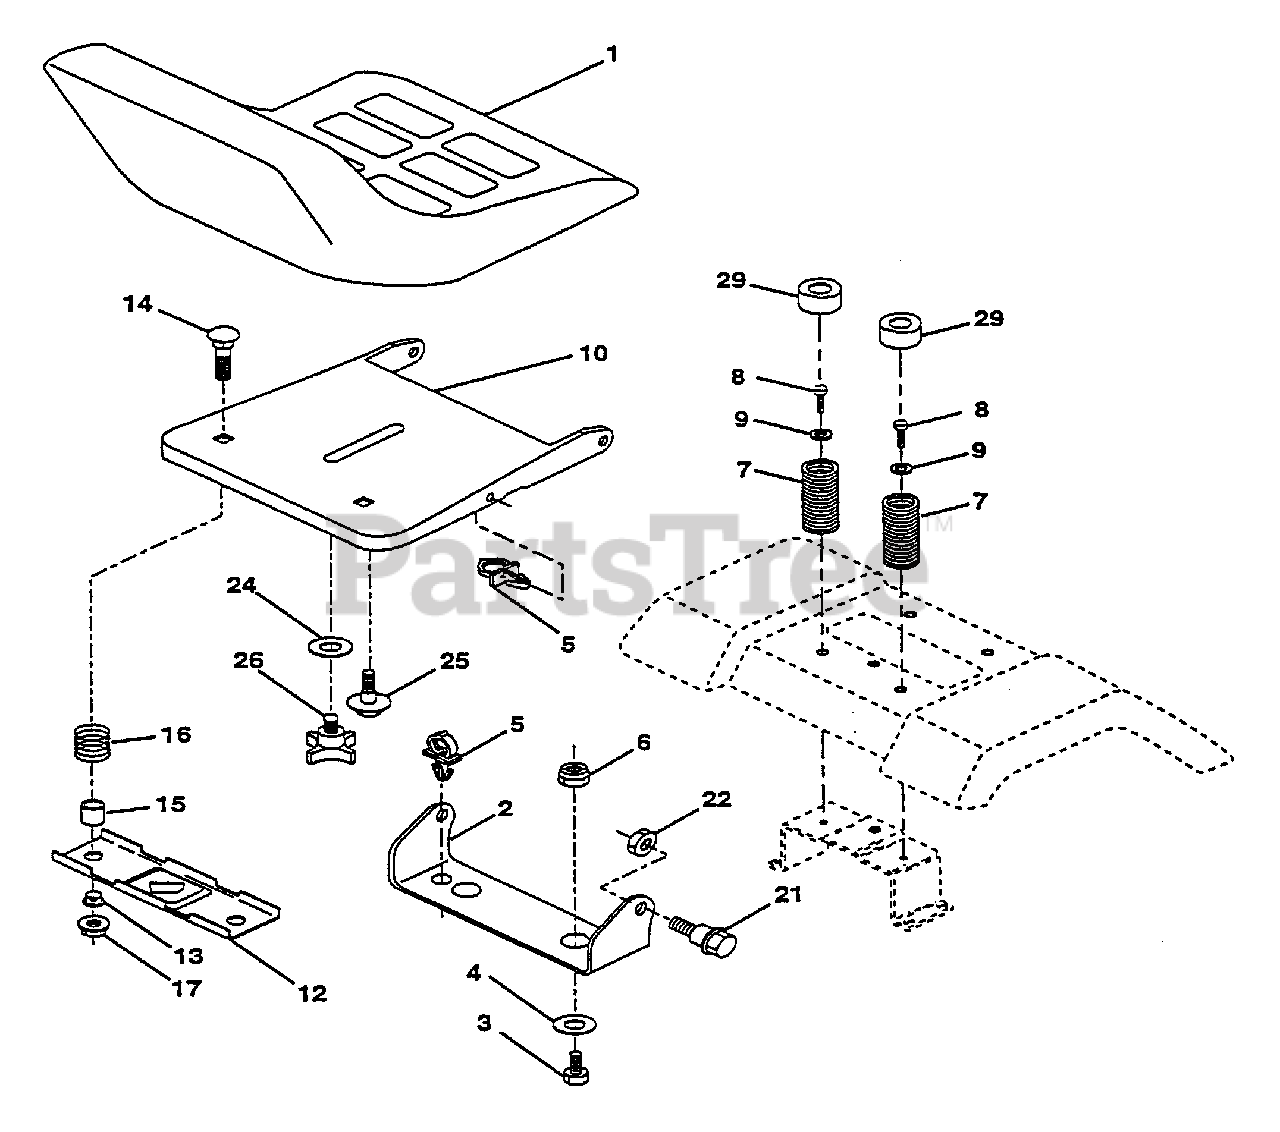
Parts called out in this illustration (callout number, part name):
1	Seat
2	Bracket Pivot Seat
3	Bolt, Hex 3/8-16unc X 2-1/2
4	Washer 13/32 X 1 X 10 Ga
5	Clip Push in .375 x .250
6	Nut, Crownlock 3/8-16 Unc
7	Spring Seat Cprsn
8	Screw Hwsh Thdrol 3/8-16x1
9	Washer 13/32 X 1 X 14 Ga
10	Pan Seat
12	Bracket Mounting Switch
13	Bushing Snap
14	Bolt 1/4-20x1-3/8
15	Spacer Split
16	Spring Cprsn
17	Locknut 1/4 Gr. 5
21	Bolt, Shoulder 5/16-18 Unc
22	Nut, Crownlock 5/16-18
24	Washer 17/32 X 1-3/16 X 12 Ga
25	Bolt, Shoulder 5/16-18 X 62
26	Knob Seat 1/2-13unc
29	Cap Spring Seat
